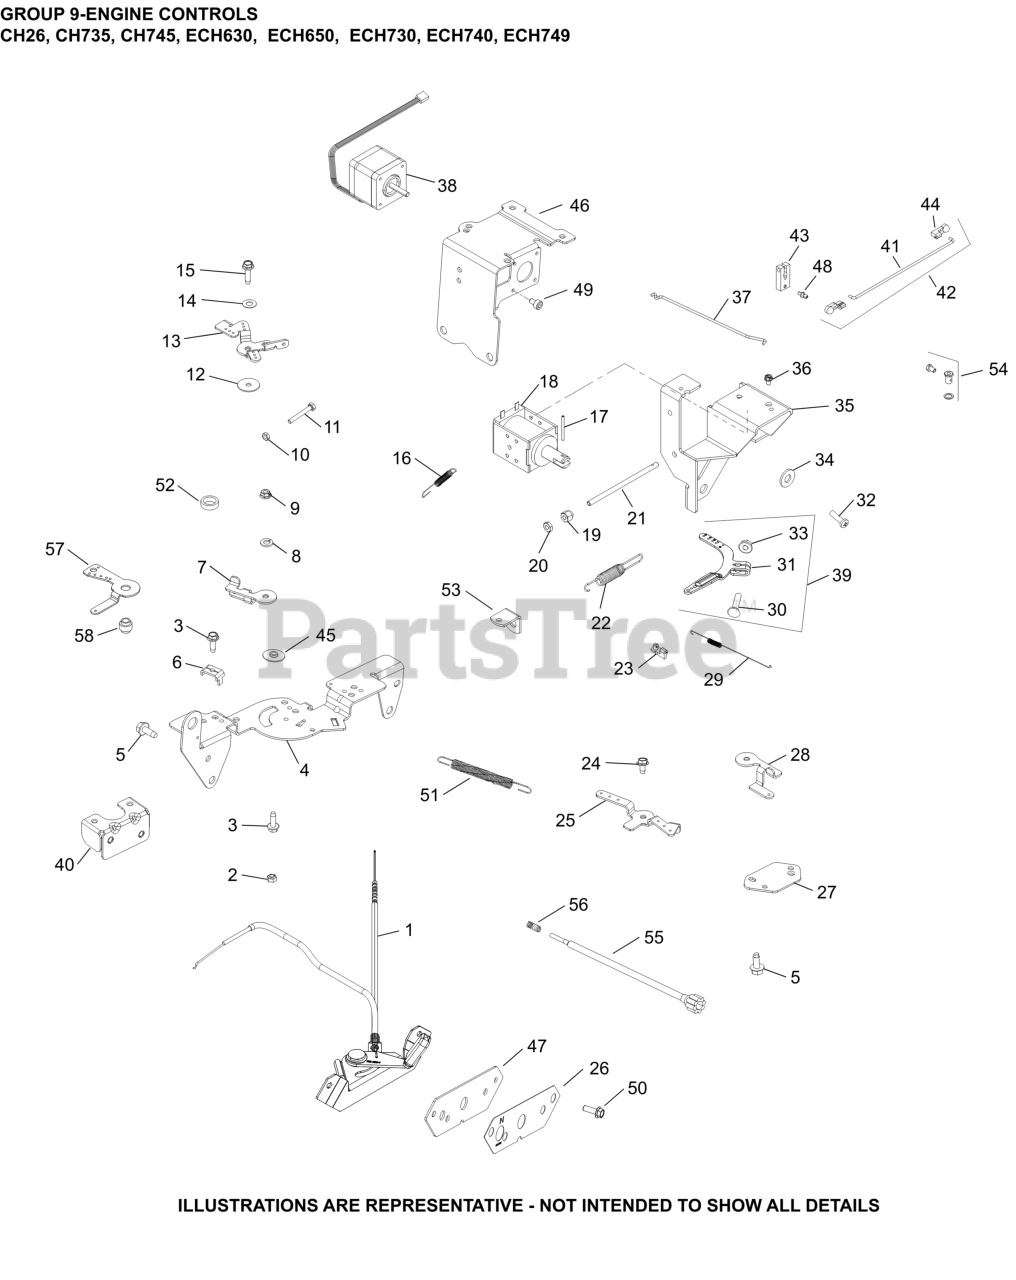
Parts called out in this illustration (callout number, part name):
2	NUT, LOCK M5X.8
3	SCREW, THREAD FORMING
4	BRACKET, CONTROL
5	SCREW, THREAD FORMING
6	CLAMP, CABLE CABLE
8	WASHER, SPRING LOCK 1/4"
9	NUT, FLG M5X.8
10	NUT, M4X0.7
11	SCREW, CAP M4X.7X30
12	WASHER, FLAT 5.5 MM
13	LEVER, THROTTLE CONTROL
14	WASHER, SPRING 1/4"
15	SCREW, THD FRM-USE 25 086 473-S
16	SPRING, THROTTLE LIMITER
22	SPRING, GOVERNOR (RED)
23	BUSHING, THROTTLE LINKAGE
28	LEVER, THROTTLE ACTUATOR
29	SPRING, LINKAGE
30	BOLT, RD HD SQ NECK M6X1.0X25
31	LEVER, GOVERNOR - (#2409069S)
33	NUT, FLG M6X1.0
37	LINKAGE, THROTTLE
39	LEVER, GOVERNOR ASSEMBLY
